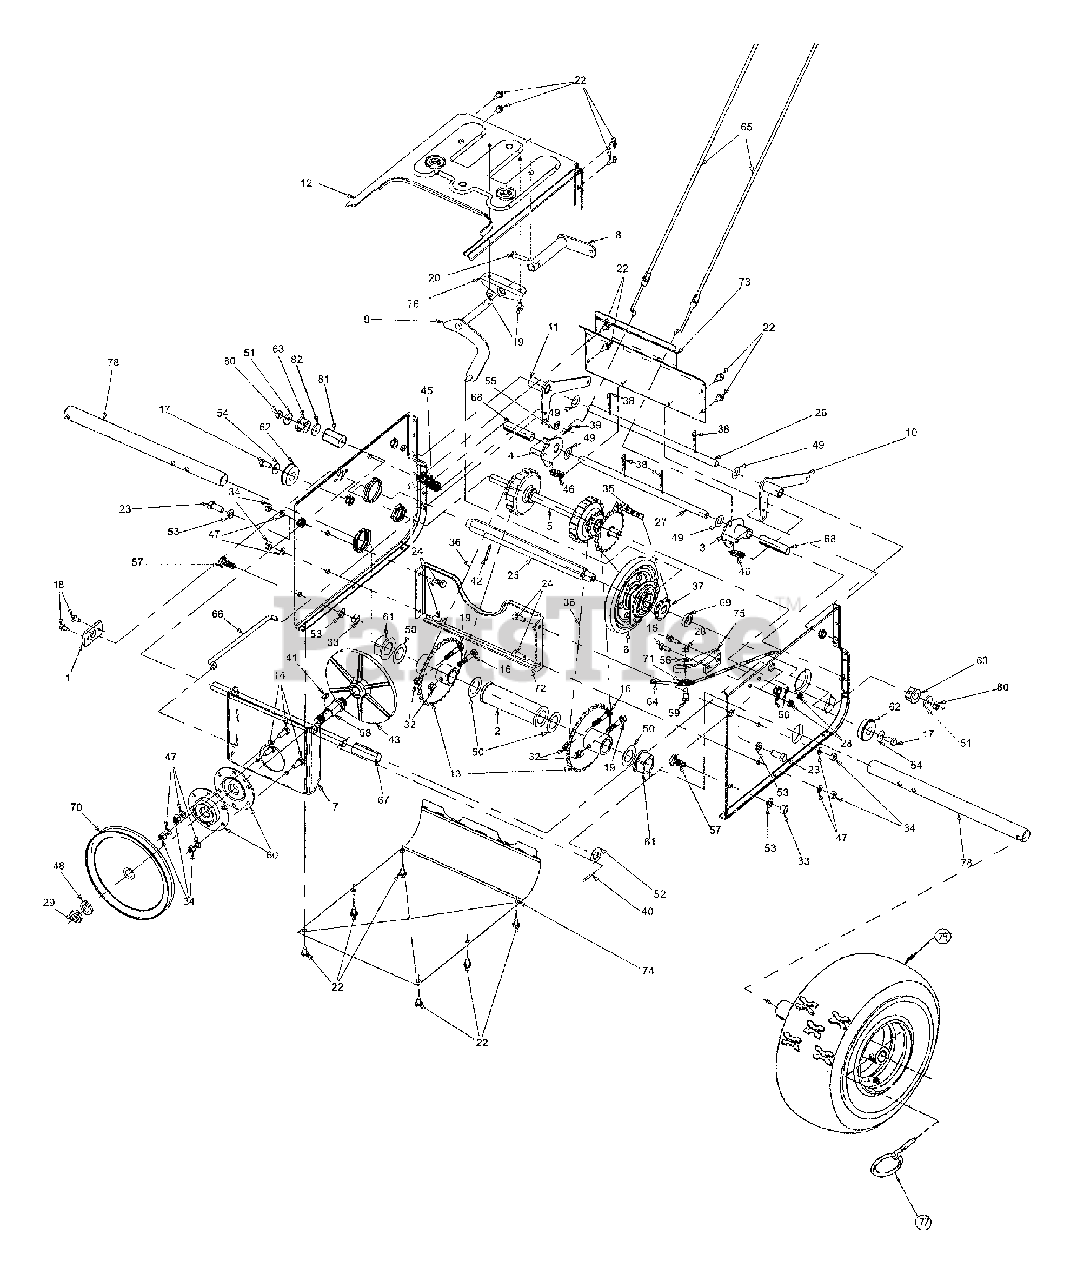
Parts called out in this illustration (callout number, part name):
1	Pivot Axle Brkt. .63 Hole - Zinc
2	Bush Asm slev
3	Dogg Asm Dr Lh
4	Dogg Asm Dr Rh
5	Shf Asm Dr
6	Whl Asm Brg 6.0 OD Friction
7	Brkt Asm Supt Friction Dr
10	Brkt Asm Actr Auger
11	Brkt Asm Actr Dr
14	Hex Scr 5/16-18 x .75
15	Hhcs 1/4-28 .625 Gr5 std
16	Hex Scr 5/16-18 x 2.00
17	Hhcs 5/16-18 x .625 Gr5 Lock
18	Scr TT 1/4-20 x .5 Hxindwsh
19	Hex Scr 5/16-18 2.00 Lg
20	Scr Hexwash 1/4-20 x 2.00
22	Scr Ab 1/4-20 .625 Hxindwsh
23	Hhcs 3/8-16 x .880 Gr5 Std
24	Scr Cap 5/16-18 x .75 Gr 5
25	Shf Dr .875 Hex
26	Shf Sctr
27	Shf Actr Dr
28	Hex Nut 1/4-28
29	Hex Ins Jam L-nut 5/8-18
32	Hex Ins L-nut 5/16-18
33	Hex Nut 3/8-16
34	Nut Hex 5/16-18 Gd 5
35	#41 Chain 1/2 Pitch x 36 L
36	#420 Chain 1/2 Pitch x 40 L
37	Spkt 10t #41 x .500
38	Internal Cot-pin 1/2 Dia
39	Intern Cot-pin 5/16 Dia
40	Cotter Pin 1/8 Dia x 1
41	#61 Hi-pro-key 3/16 x 5/8
42	Spring Pin Roll 5/32
43	Aluminum Drive Plate
45	Idler Extension Spring
46	Extension Spring
47	Lock Washer 5/16
48	Lock Washer 5/8
49	Wash Fl .531 ID x .930 OD x .05
50	Wash Fl 1.03 ID x 1.62 OD
51	Wash Flt 1/4 ID x .930 OD x .12
52	Wash Flt .640 ID x 1.24 OD x .06
53	Lock Washer 3/8 Heavy
54	Bell Wash .345 ID x .88 OD
55	Fl-wash Sae .34 x .68 .062
56	Lock Washer 1/4
57	Shld Scr .498 Dia x .340
58	Drive Plate Spindle
59	Scr Shldr .340 D. 1/4 Ab
60	Asm Brg Hsg
61	Flange Brg Pm W/flts 1.0
62	Ball Bearing W/snap Ring
63	Brg Hex Flange x .564 ID
64	Cb Idlr Auger
65	Cbl Strg
66	Rod Clu Dr
67	Spcr Splt .64 x .77 x 2.1
68	Split Spacer 1/2 x 5/8 x 2.44
69	Spcr .675 ID x 1.00 OD x .23
70	112 V-pulley .62 ID x 7.5
71	Cable Guide Roller
72	Brkt Supt Frm
77	Klik Pin Assy Danuse
78	Axle 1.0 OD x 14.1 Lg
80	Jam L-Nut 3/8-24 Thd.
81	Spacer
82	Fl-Washer
